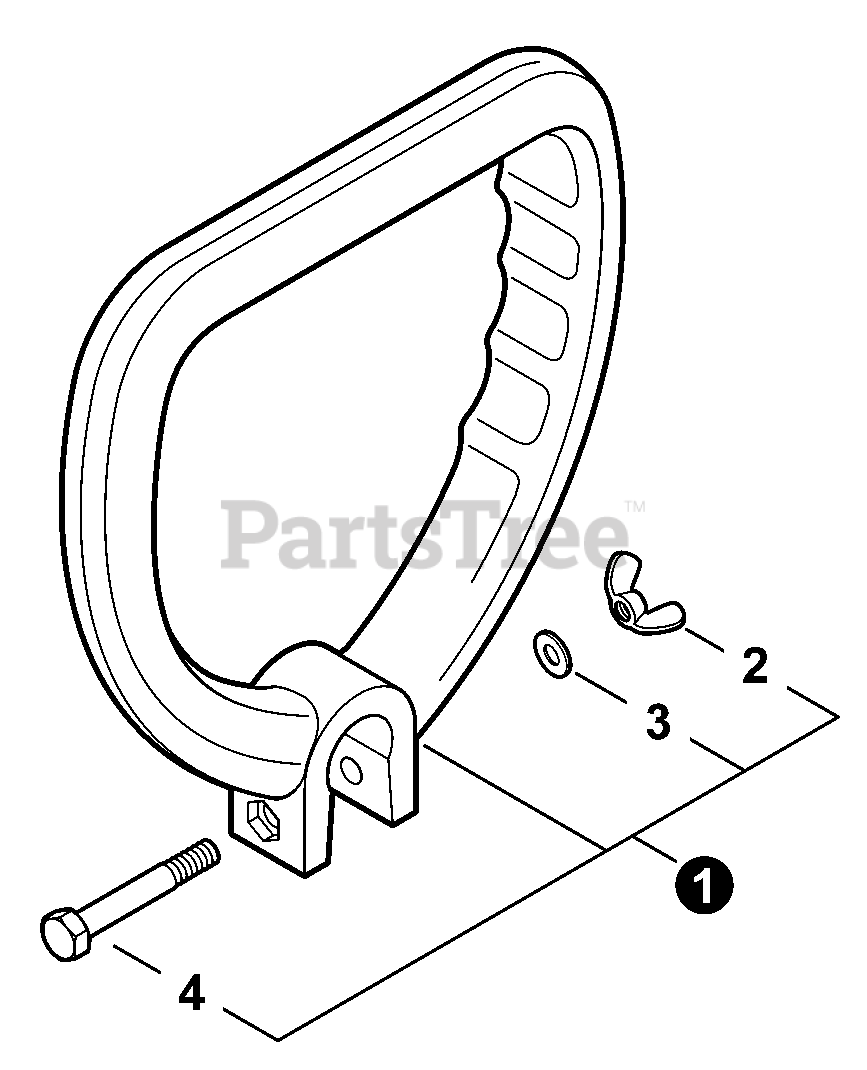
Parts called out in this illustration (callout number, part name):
1	HANDLE ASSY
2	NUT, WING 1/4"-20
3	WASHER, 1/4"
4	BOLT 6×45
